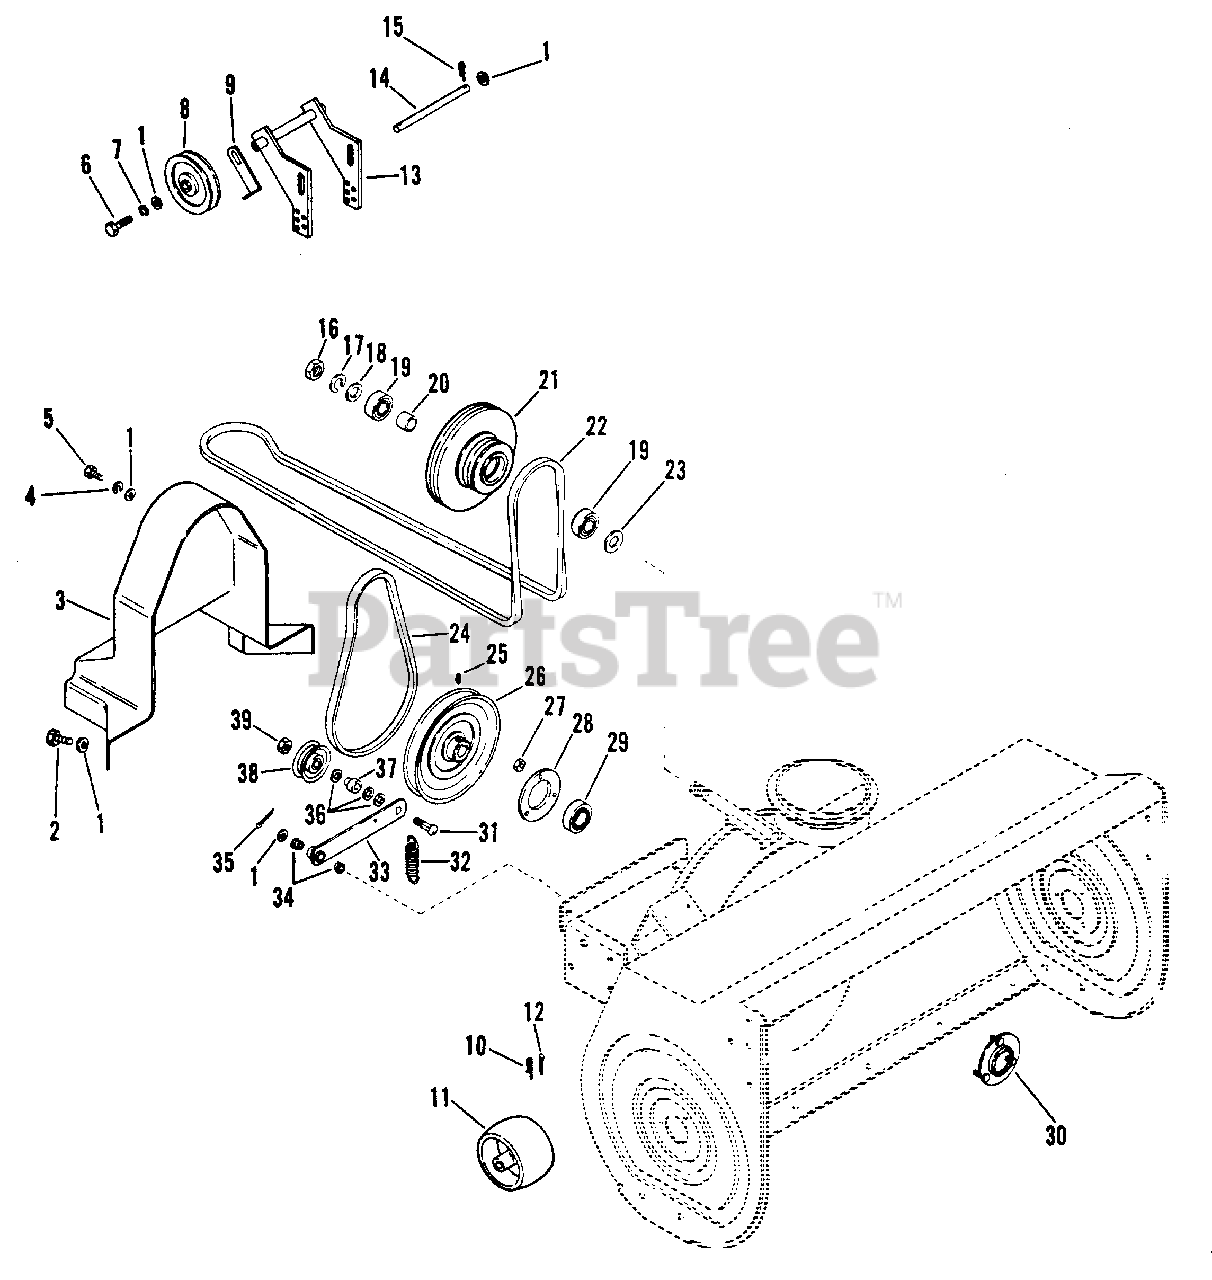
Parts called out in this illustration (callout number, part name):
1	Washer, Flat .406x.812x.065
2	Taptite 3/8-16x1/2
3	Belt Guard
4	Washer, Lock 5/16 SP
5	Bolt, Hex 5/16-18x.75
6	Bolt, Hex 3/8-16x1.50
7	Washer, Lock 3/8 Reg.
8	Idler 3/8x4"
9	Belt Retainer
10	Hair Pin
11	Roller
12	Pin, Cotter 3/32x.75
13	Idler Bracket
14	Pin
15	Hair Pin, Internal 3/32
16	Nut, Jam 3/4-10
17	Lock Washer, Internal 3/4
18	Washer .774/.811x1.250x16 Ga.
19	Radial Bearing 3/4x1-25/32
20	Spacer
21	Pulley
22	V-Belt 4L-RMA 140 1/4x17/32
23	Washer .774/.811x1.500x.188
24	V-Belt 4L-RMA 36 15/64x17/32
25	Set Screw 5/16-18x1/2
26	Pulley 5/8x7-1/2
27	Nut, Lock 1/4-20
28	Bearing Flange
29	Ball Bearing 1" I.D.x2" O.D.
30	Bearing Flange
31	Bolt, 3/8-16x1.50 Rd Hd Sq Nk
32	Extension Spring 3-1/2
33	Idler Arm
34	Flange Bushing 3/8x1/2x5/16
35	Pin, Cotter 1/8x3/4
36	Washer, Flat .531x1.062x.095
37	Spacer
39	Nut, Lock 3/8-16
